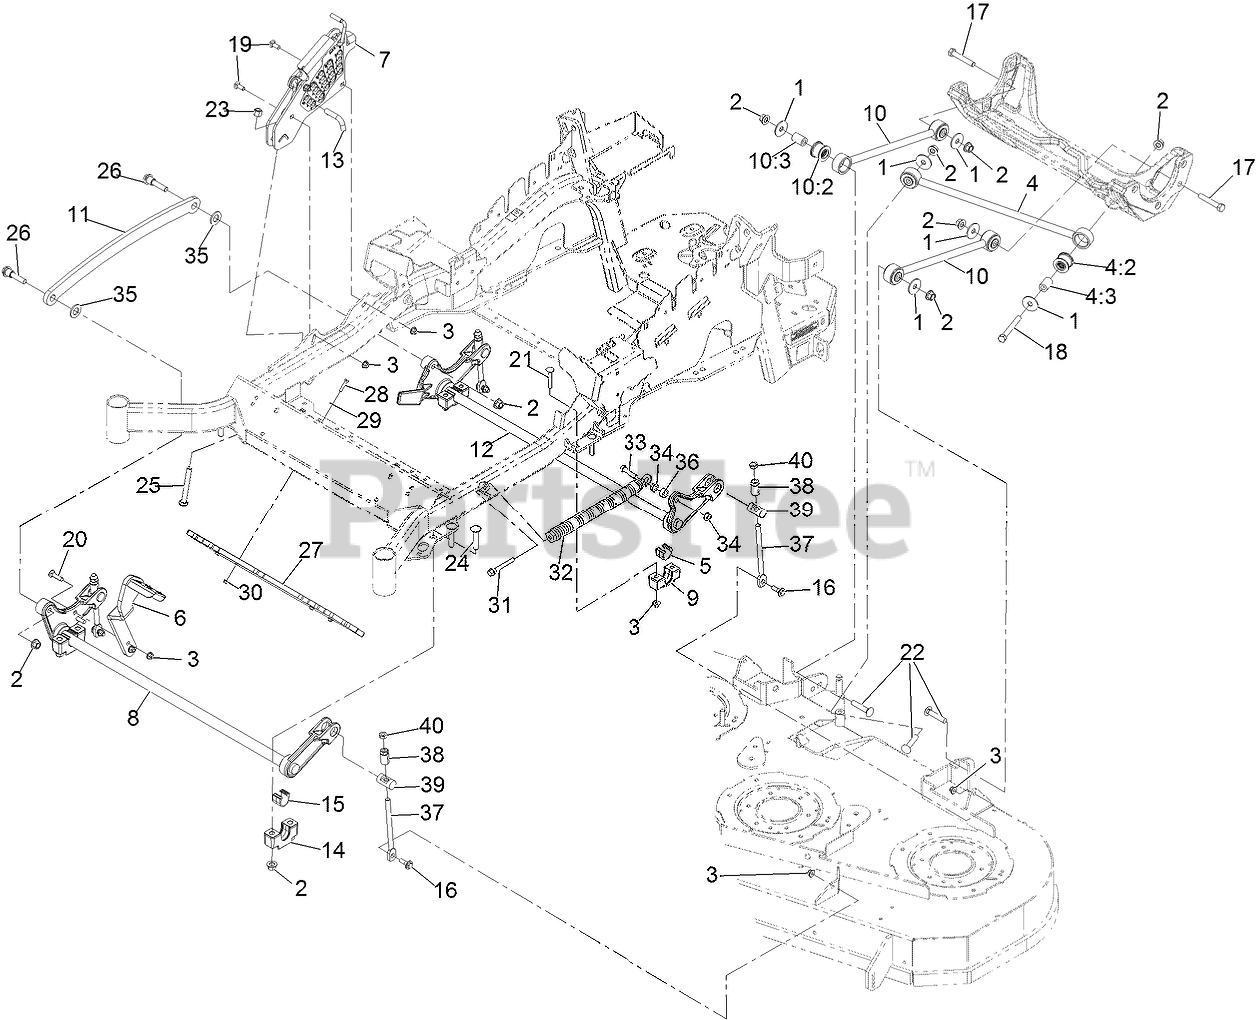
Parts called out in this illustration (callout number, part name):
1	WASHER-THRUST
2	Nut-Lock 1/2-13
3	NUT-HF, NI
4	PANHARD ROD ASM
4:2	BUSHING-SUSPENSION, RUBBER
5	BEARING-CROSS SHAFT, REAR
6	LEVER-FOOT
7	HOC ASM
8	DECKLIFT-FRONT
9	SUPPORT-CROSS SHAFT, BEARING REAR
10	DECK STRUT ASM
10:2	BUSHING-SUSPENSION, RUBBER
11	LINK-LIFT, DECK
12	LIFT-DECK, REAR
13	PIN-HOC
14	SUPPORT-CROSS SHAFT, BEARING
15	BEARING-CROSS SHAFT, FRON
16	SCREW-SHOULDER, HHF
17	SCREW-HH
18	SCREW-HH
19	BOLT-CARR
20	SCREW-CARR
21	Bolt-Carriage 3/8-16 X 2 1/4
22	SCREW-CARR
23	NUT-LOCK, NI
24	Bolt-Carriage 1/2-13 X 2 1/2 Spl Neck
25	BOLT-TAP
26	SCREW-HHF, SHOULDER
27	Weight-Toe Board
28	SCREW-HH
29	WASHER-FLAT
31	BOLT-SHOULDER
32	SPRING-EXTENSION
33	SCREW-HH
35	WASHER-FLAT
37	LINK-ADJUSTER, DECK LIFT
38	ADJUSTER-LIFT, DECK
39	TRUNNION
40	NUT-JAM
